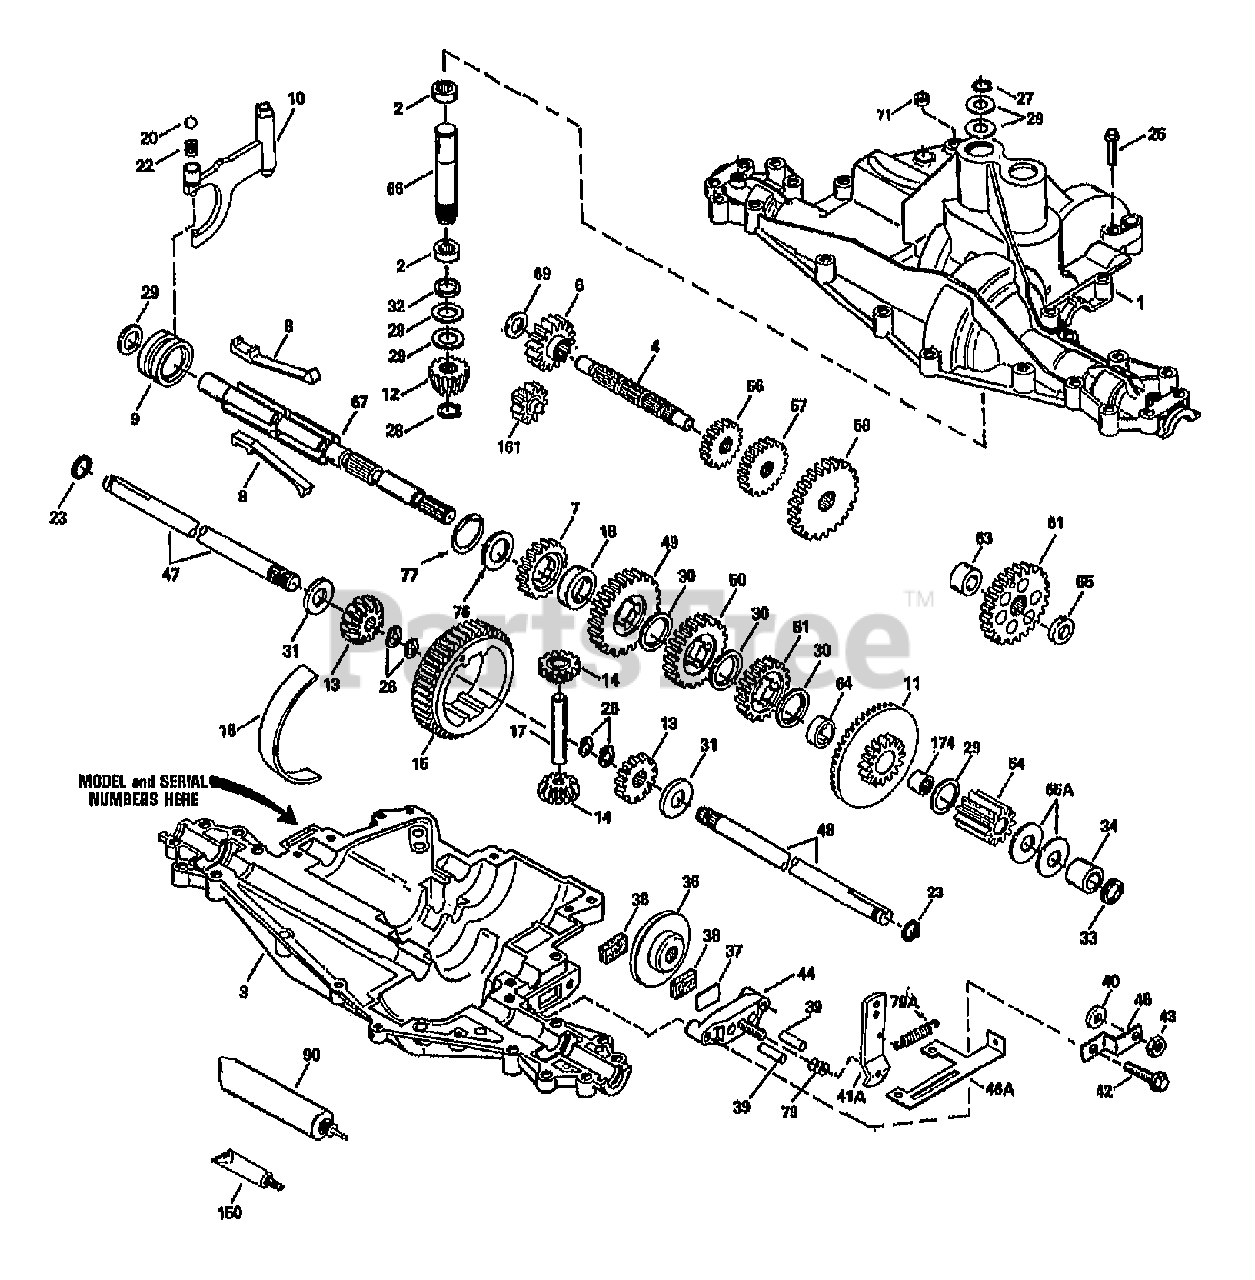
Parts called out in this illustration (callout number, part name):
1	TRANSAXLE COVER
2	NEEDLE BEARING
3	TRANSAXLE CASE
4	COUNTERSHAFT
6	SPUR GEAR (16 TEETH)
7	SPUR GEAR (22 TEETH)
8	SHIFT KEY
9	SHIFT COLLAR
10	SHIFT ROD & FORK
11	BEVEL GEAR & BEARING (INCL. 174)
12	BEVEL PINION (14 TEETH)
13	BEVEL GEAR (16 TEETH)
14	DIFFERENTIAL PINION
15	RING GEAR
16	BEARING STRIP
17	DRIVE PIN
18	NEUTRAL SPACER
20	STEEL BALL, 5/16" DIA.
22	SPRING
23	SEAL RING
25	SCREW, 1/4-20 X 1-1/4"
26	RETAINING RING
27	RETAINING RING
28	RETAINING RING
29	WASHER
30	WASHER
32	"O" RING
33	"O" RING
36	BRAKE DISK
37	BRAKE PAD PLATE
38	BRAKE PAD (PKG. OF 2)
39	DOWEL PIN
41A	BRAKE LEVER
42	SCREW, 1/4-20 X 1-1/4"
43	LOCKNUT, 5/16-24
44	BRAKE PAD HOLDER
46	BRAKE LEVER BRACKET
46A	BRAKE BRACKET
49	SPUR GEAR (32 TEETH)
50	SPUR GEAR (27 TEETH)
51	SPUR GEAR (25 TEETH)
54	SPUR GEAR (11 TEETH)
56	SPUR GEAR (18 TEETH)
57	SPUR GEAR (23 TEETH)
58	SPUR GEAR (25 TEETH)
61	SPUR GEAR (34 TEETH)
64	OUTPUT SHAFT SPACER
66	INPUT SHAFT
67	SHIFTER & BRAKE SHAFT
71	SQUARE CUT RING
77	INVERTED RETAINING RING (PKG. OF 2)
79A	BRAKE RETURN RING
90	GREASE (32 OZ. BTL. BENTONITE GREASE)
150	GASKET ELIMINATOR (LOCTITE #515)
161	REVERSE IDLER
174	NEEDLE BEARING
